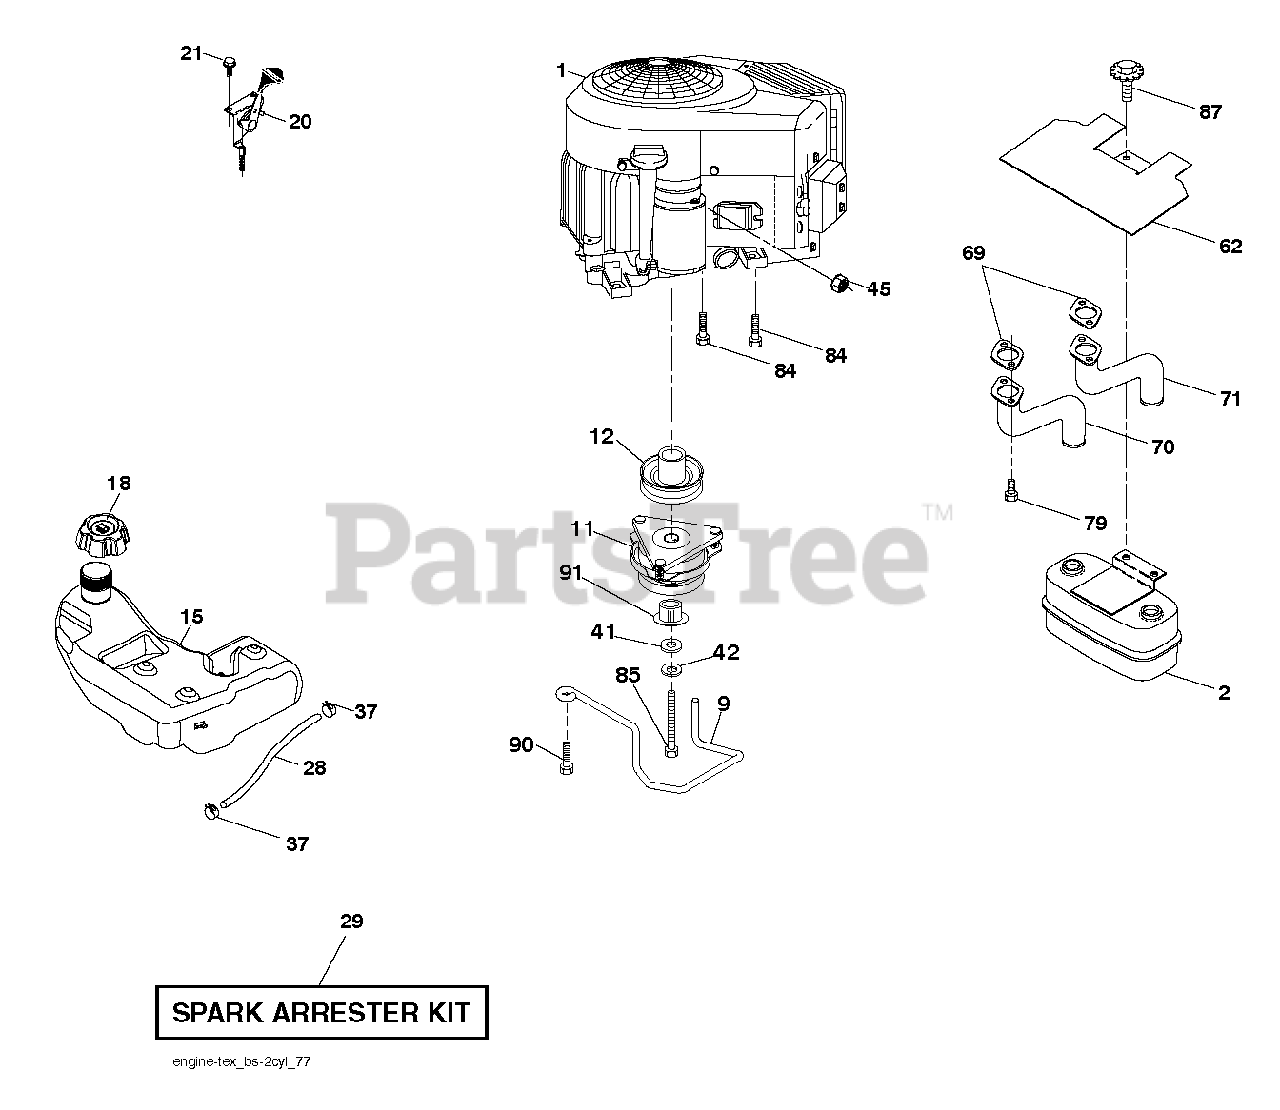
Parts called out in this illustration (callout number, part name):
2	MUFFLER.ASM.TWN.EXTNDED.DFLCTR
9	KEEPER.BELT.ENGINE.4.2
11	CLUTCH MZ ZTR GT.48/54"1.125"
12	PULLEY ENGINE
15	TANK.FUEL.4GAL
18	CAP.FL.R.3'N/CARB.H.CROWN.498
20	CONTROL.TH/CK.COBRA.B&S.TWN.
21	SCREW.#10 X 0.750.BOS
28	REPL BY 532 00 85-43
29	KIT.SPARK ARRESTOR 794945 B&S
37	HOSE CLAMP
42	LOCKWASHER
45	NUT
62	SHIELD.HEAT.MUFFLER
69	GASKET.MUFFLER
70	RP.EXHAUST.TUBE.LH.BS/TWIN
71	EXHAUST.TUBE.RH.BS/TWIN
79	SCREW.SOCKET.HEAD.5/16-18
84	SCREW.3/8-16
85	BOLT HEX 7/16-20 X 3.75 GR. 5
87	BOLT, 5/16-18 X 1 3/4
90	SCREW 3/8-16X1
91	BUSHING.1.375OD
